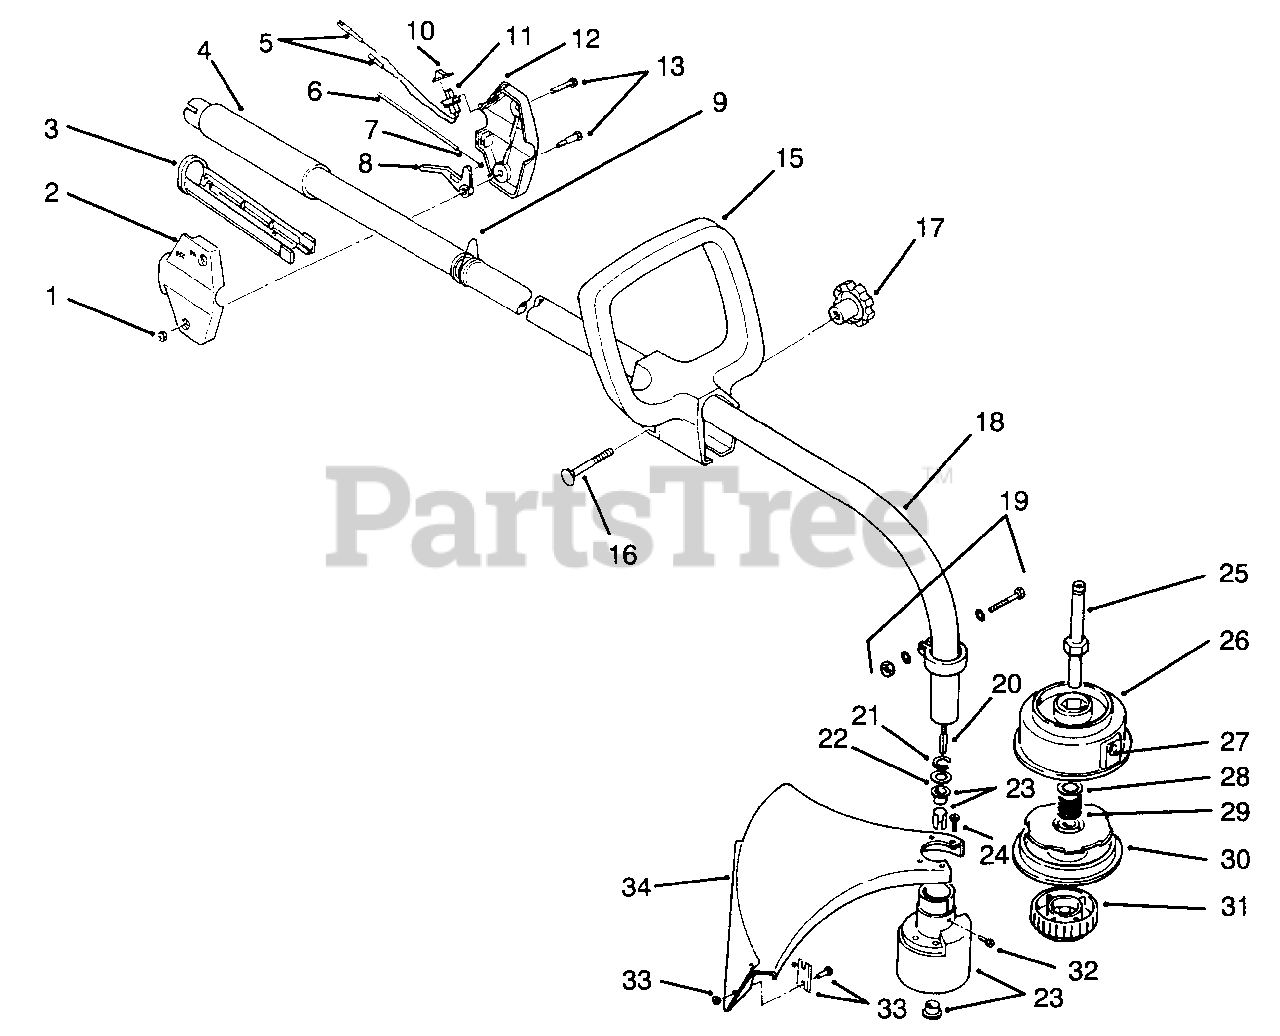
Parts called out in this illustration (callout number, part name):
1	Nut-Lock
2	Housing-R.H.
5	Assembly-Lead Wire
6	Housing-Throttle Cable
7	Cable-Throttle
8	Lever-Throttle
9	Clamp-Shoulder Strap
10	Cap-Switch
12	Housing-L.H.
13	Screw-Hex. Hd.
16	Bolt-Carriage
17	Knob-Loop Handle
18	Assembly-Drive Shaft
19	Assembly-Lower Clamp
20	Flexible Drive Shaft
21	Ring-Retaining
23	Assy.-Bushing Housing
24	Assy.-Guard Mount Screw
25	Shaft-Spool
26	Assy.-Outer Spool & Eyelet
28	Retainer
30	Inner Reel
31	Assy.-Bump Head Knob
32	Anti-Rotation Screw
33	Assembly-Blade (Incl.2 Screws/2 Nuts)
34	Assembly-Guard & Blade (Incl. Ref. # 33)
